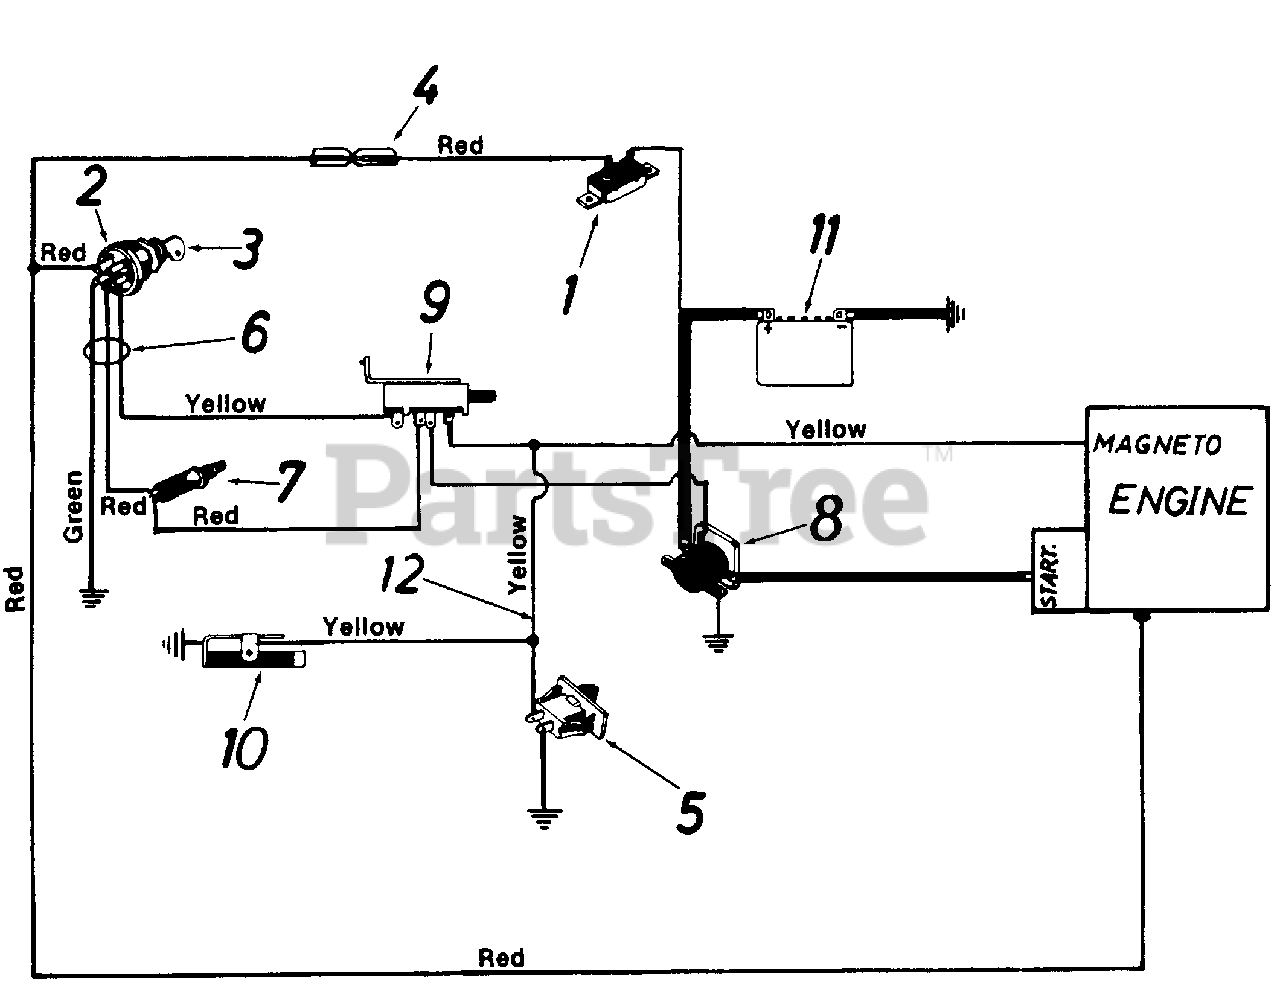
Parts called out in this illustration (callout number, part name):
1	Circuit Breaker
2	Ignition Switch
3	Ignition Key
4	Insulated Tab Adapter
5	Satety Switch
6	Wire Harness
7	Satety Switch
8	Solenoid
9	Satety Switch
10	Spring Switch
11	12V Battery
12	Wire Lead
